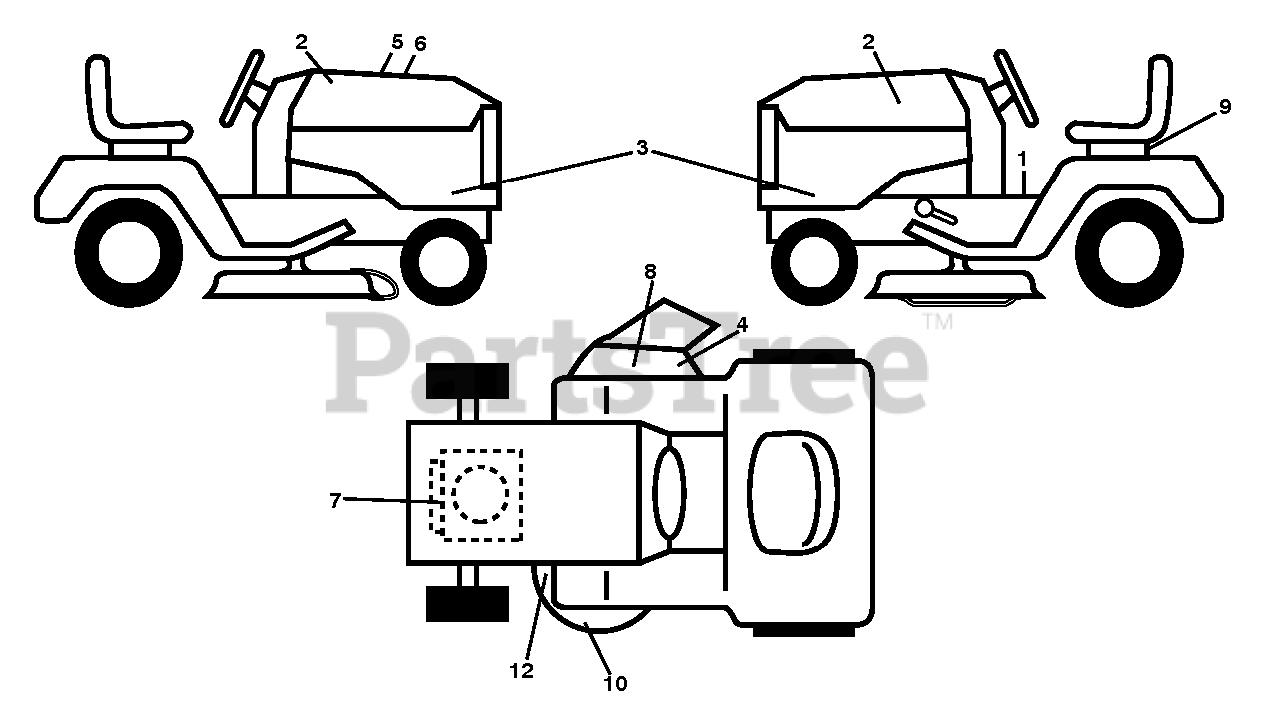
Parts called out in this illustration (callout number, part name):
1	DECAL.FENDER.WARNING.ENGLISH
2	DECAL.BADGE.170MM.TEXTLOGO.
3	DECAL.SIDE.PANEL.YTH22V46.2013
4	DECAL, DECK DEFLECTOR, WARNING
5	DECAL.WARNING.CUST.RESP.E85.
6	DECAL.RPL.BSM44.END.TLW.46C.K4
7	DECAL DECAL.ENG.BS.ENDUR.22HP.
8	DECAL, DECK DEFLECTOR, WARNING
9	DECAL BTRY SYMBOLS
12	DECAL.V-BELT.SCH.42/46"MEC/ELE
